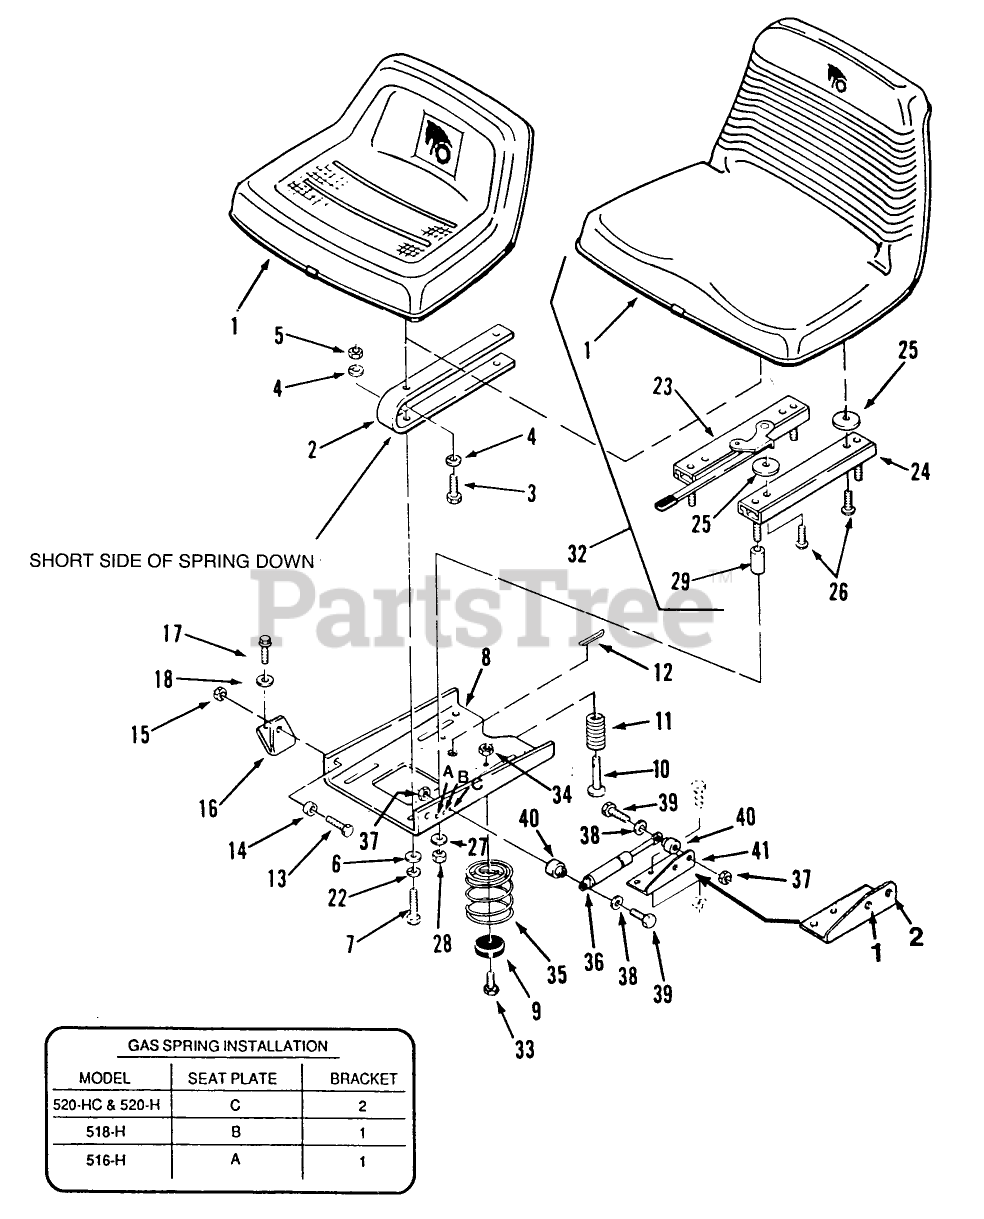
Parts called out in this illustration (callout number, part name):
6	WASHER 5/16 SAE
9	BUMPER
11	SPRING-SEAT SWITCH
14	BUSHING
16	BRACKET-PIVOT R.H *B (NS)
25	SPACER-NYLON
36	GAS SPRING
40	SPACER
41	BRACKET-CYLINDER *R
